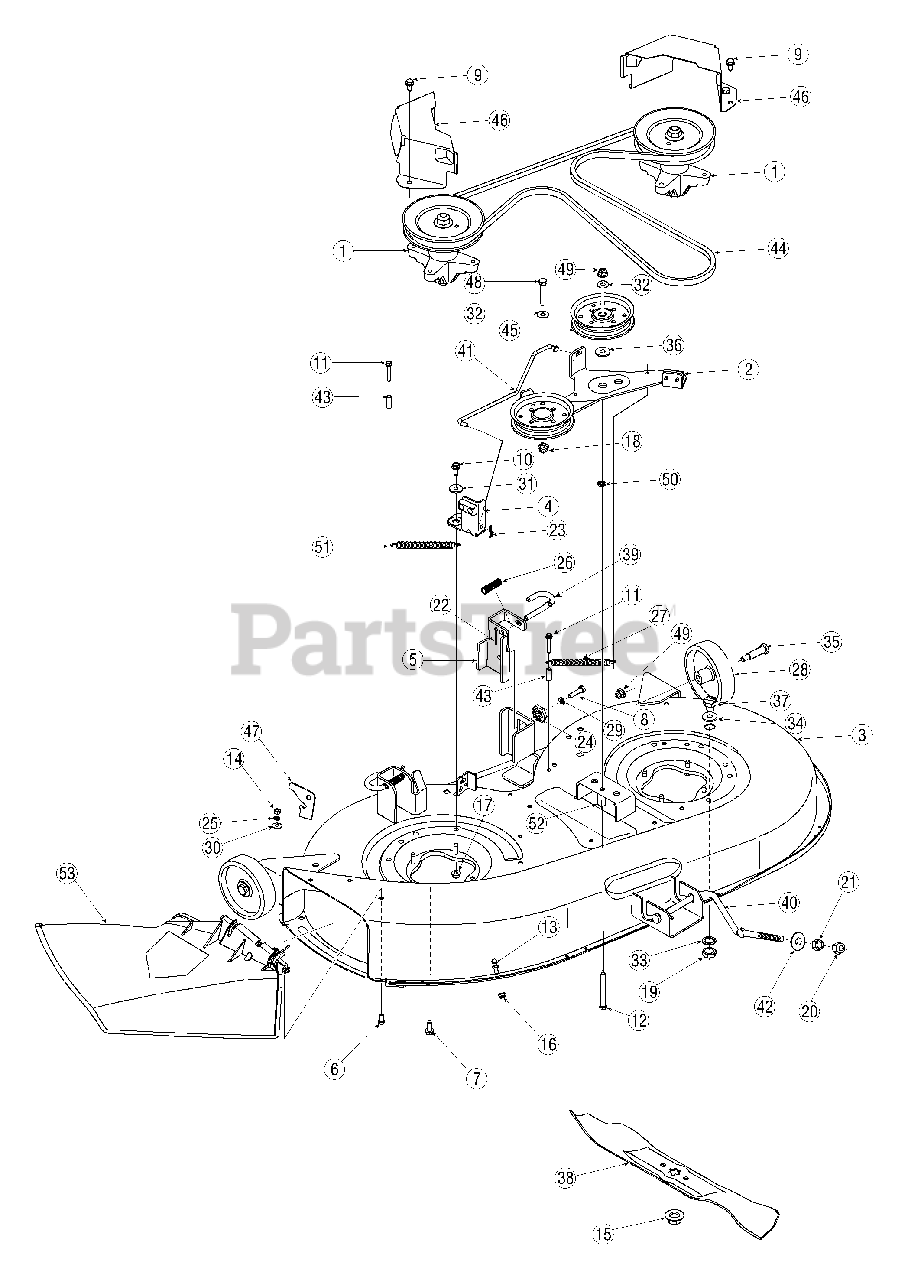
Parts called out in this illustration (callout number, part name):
1	Pulley/ Spindle Assembly
6	Screw, 1/4-20 x.620
7	Screw, 5/16-18 x.875
8	Screw, 5/16-18 x 1.25
9	Screw, 5/16-12 x.750
10	Screw, 5/16-18 x.750
11	Screw, 1/4-20 x 1.500
12	Screw, 3/8-16 x 3.50
13	Grass catcher Pin
14	Hex Nut, 1/4-20
15	Flange Nut, 5/8-18
16	Flange Lock Nut, 1/4-20
17	Flange Lock Nut, 5/16-18
18	Flange Lock Nut, 3/8-16
19	Hex Nut, M16-1.5
20	Hex Lock Nut, 1/2-13
21	Hex Nut, 1/2-13
22	Cotter Pin, 1/8 x 1.25
23	Cotter Pin,.072 Dia. x 1.13 Lg.
24	Deck Adjustment Gear
25	Push Nut,.25 ID x.50 OD
26	Compression Spring,.531 OD x 1.
27	Extension Spring,.50 Dia. x 6.37 Lg.
28	Deck Wheel
29	Lock Washer, 5/16
30	Bell Washer,.265 x.75 x.062
31	Shoulder Bushing,.320 ID x.135 Lg.
32	Flat Washer,.385 x.87 x.06
33	Lock Washer, 5/8
34	Flat Washer,.64 x 1.24 x.06
35	Shoulder Screw,.498 x 1.53 x 3/8-16
36	Shoulder Spacer,.8540 x.200
38	Blade, 21.23", Star 3-in-One
39	Deck Release Handle Rod
40	Front Deck Adjustment Rod
41	Brake Control Rod
42	Deck Lift Pivot Cup
43	Spacer,.260 x.372 x 1.030 Lg.
44	V-Belt, 96.3 Lg.
45	Idler Pulley, 4.25" Dia.
47	Chute Stop
48	Screw, 3/8-16 x 2.00
49	Flange Lock Nut, 3/8-16
50	Push Nut, 3/8
51	Extension Spring,.500 Dia. x 6.375 Lg
52	Spacer, 3/8 ID x.68 OD x 1.46 Lg
53	Discharge Chute
